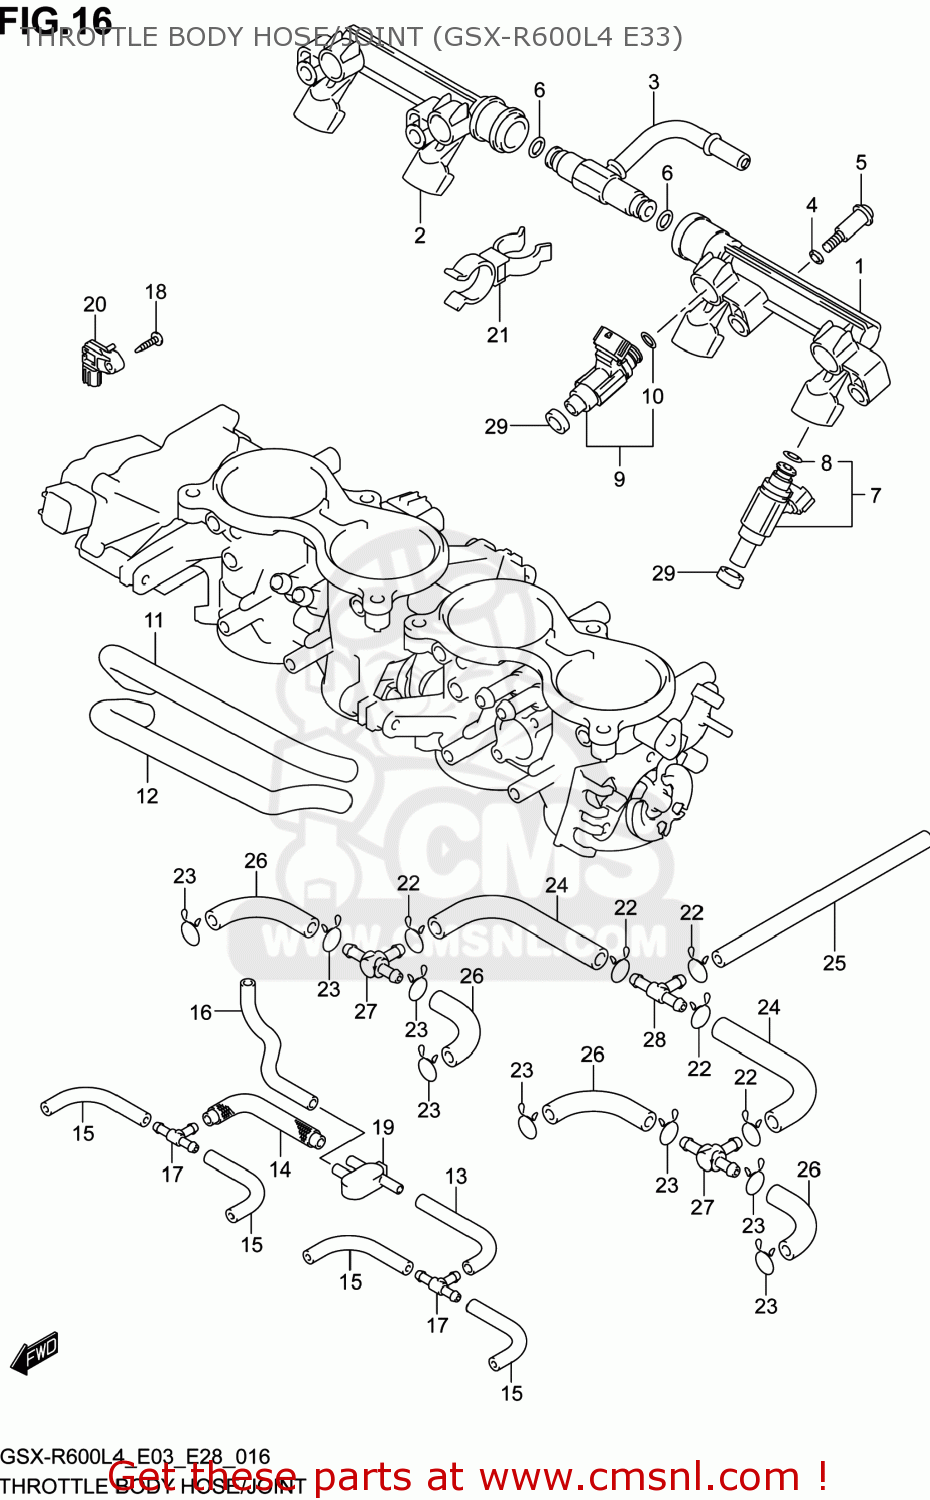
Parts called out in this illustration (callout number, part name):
1	DELIVERY PIPE
2	DELIVERY PIPE
3	NIPPLE ASSY
4	PACKING (NAS)
5	SCREW
6	O RING
7	INJECTOR ASSY
8	O-RING
9	INJECTOR ASSY
10	O-RING
11	HOSE
12	HOSE
13	HOSE
14	HOSE
15	HOSE(L:425)
16	HOSE
17	3WAY,VACUUM HOSE
18	SCREW
19	JOINT
20	SENSOR,BOOST
21	CLAMP
22	CLIP
23	CLIP
24	HOSE
25	HOSE
26	HOSE
27	NIPPLE
28	NIPPLE
29	SEAL
